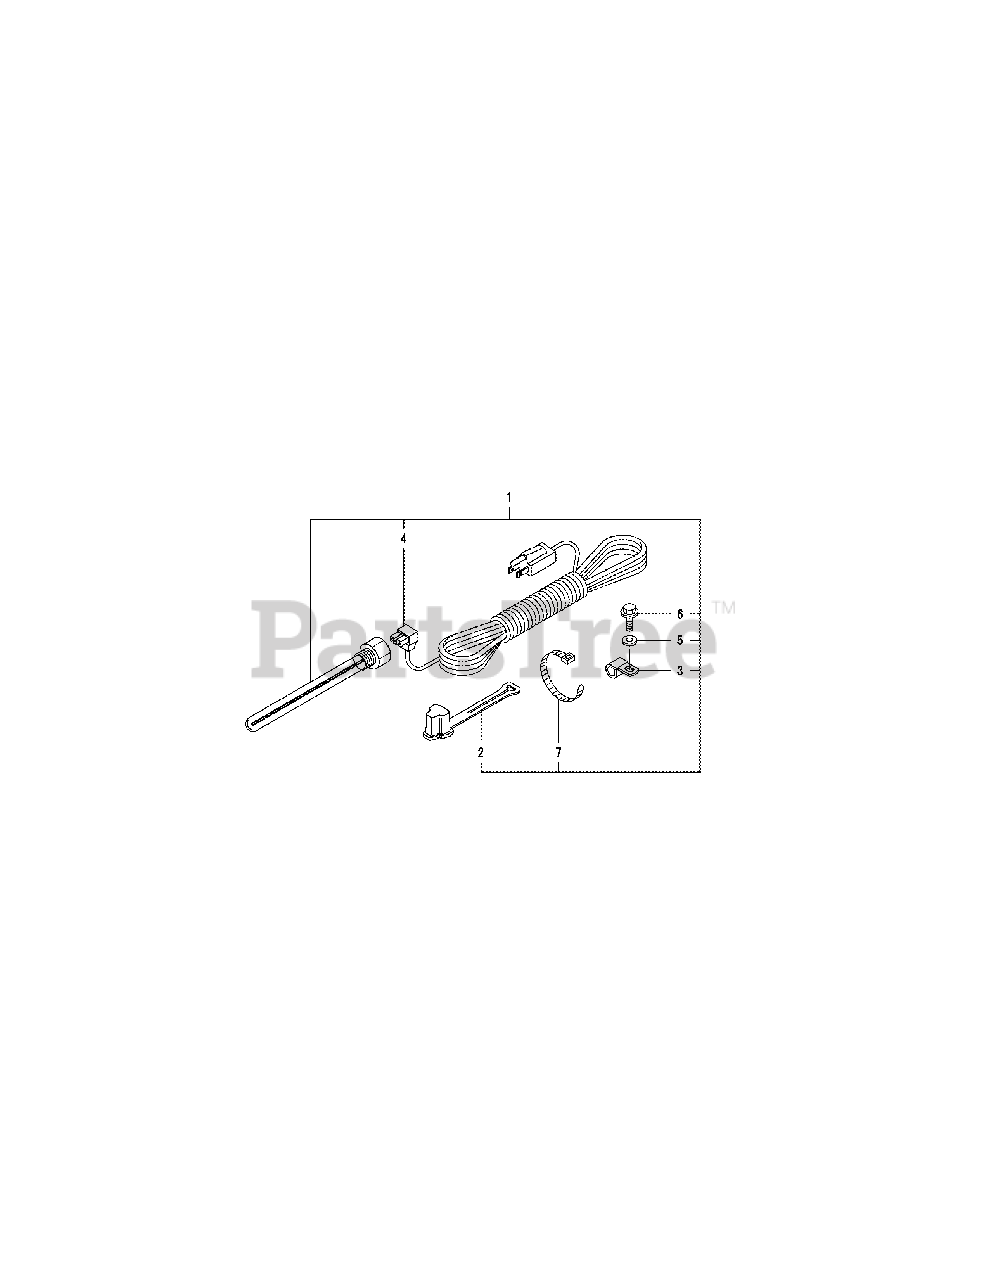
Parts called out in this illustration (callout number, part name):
1	HEATER,TM KIT
2	PLUG PROTECTOR
3	CLIP 18,HARNESS
4	POWER CODE,HEATER TM
6	BOLT M 6X 20 PLATED
